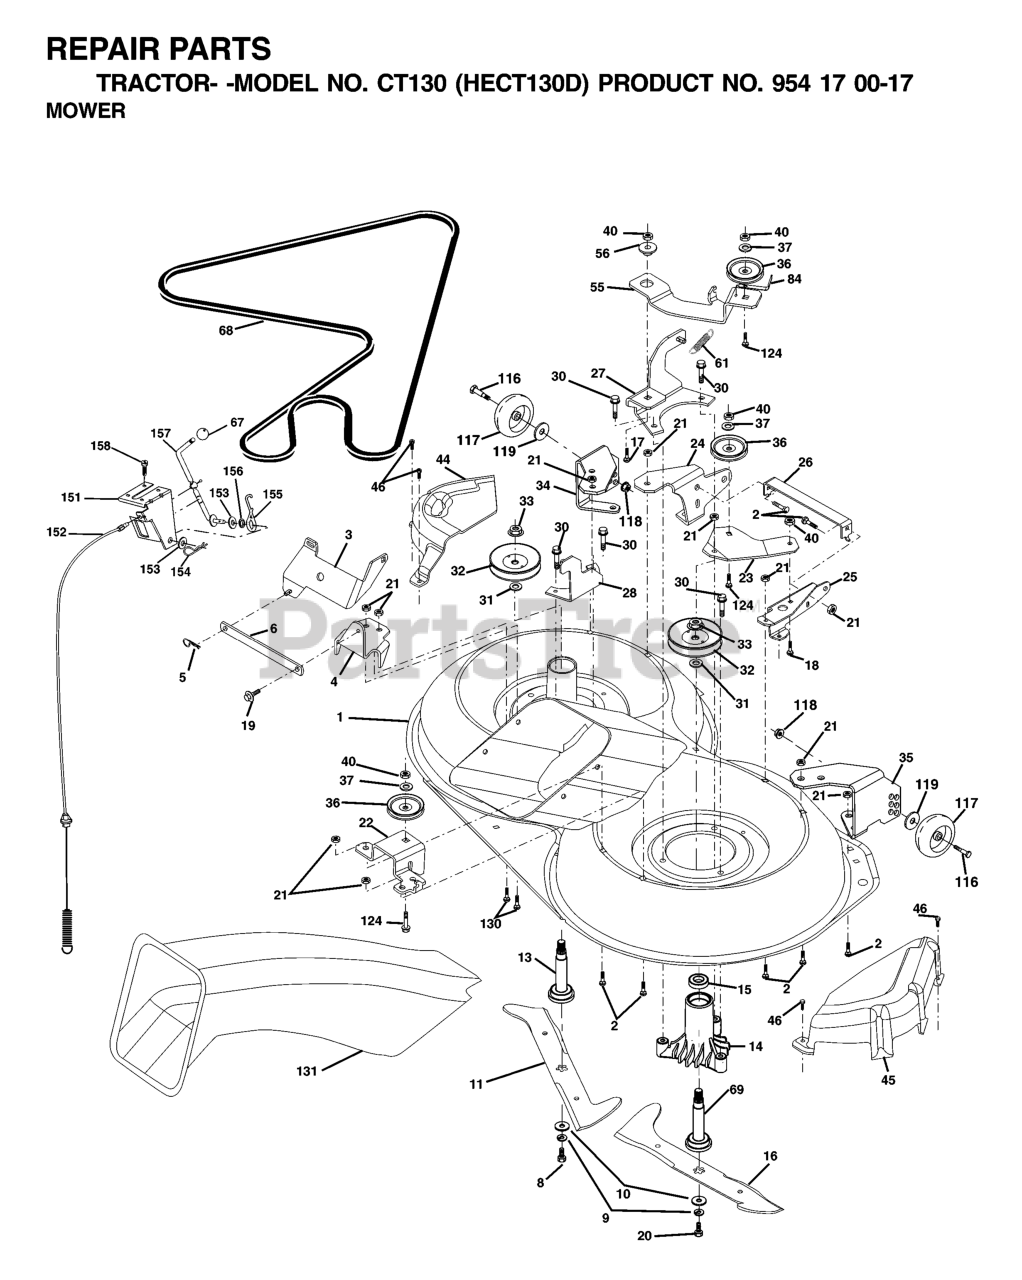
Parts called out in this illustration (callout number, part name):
1	MOWER HOUSING, DECK
2	RP BOLT 5/16-18 X3/4 ZN/YEL GR
5	RETAINER-SPRNG RB
6	BAR.SWAY.92.CRD
8	BLADE BOLT
9	LOCKWASHER
10	WASHER.BLADE
11	BLADE-LH 5PT STAR(CTH130)
12	BEARING.BALL.#6204.(MANDREL)
13	SHAFT ASM VENT
14	HOUSING.MANDREL.VENTED (MACHD)
16	BLADE RH 6PT STAR(CTH130)
17	BOLT.3/8-14X1.25
18	BOLT D
19	BOLT SHD 5/16-18
21	LOCKNUT
26	BRACE.SUPT.SUSP.FRT.CRD
30	SCREW THDROL ROLLING WASHER HD
31	WASHER
32	PULLEY, MANDREL
33	NUT
36	PULLEY.IDLER.4.25
37	WASHER
44	COVER.MANDREL.LH.92.CRD
45	COVER
46	SCREW.1/4-20X5/8
56	SPACER.RETAINER.MOWER
61	SPRING.TENSION.BELT
67	KNOB T (3/8 HOLE)
68	HEX-BELT 92 MOWER 105AA
69	SHAFT.ASM.W/LWR.BRG.RH.THREAD
84	KEEPER, BELT IDLER
116	BOLT, SHOULDER
117	WHEEL GAGE DONUT
118	LOCKNUT
119	WASHER.5/16.FLAT.STE.STD.
124	BOLT.3/8-16X1.50
128	WASHER FELT
130	BOLT.CARR.SQNK.5/16-18UNC.X3/4
131	CHUTE BAGGER
151	BRACKET.CLUTCH.CABLE
152	Cable Clutch CRD Service
153	WASHER FLAT 3/8"
154	SPRING RETAINER
155	SPRING RETENTION LEVER
156	SPACER.CLUTCH.CABLE
157	ROD CLUTCH CABLE 3/8"
158	SCREW LT
